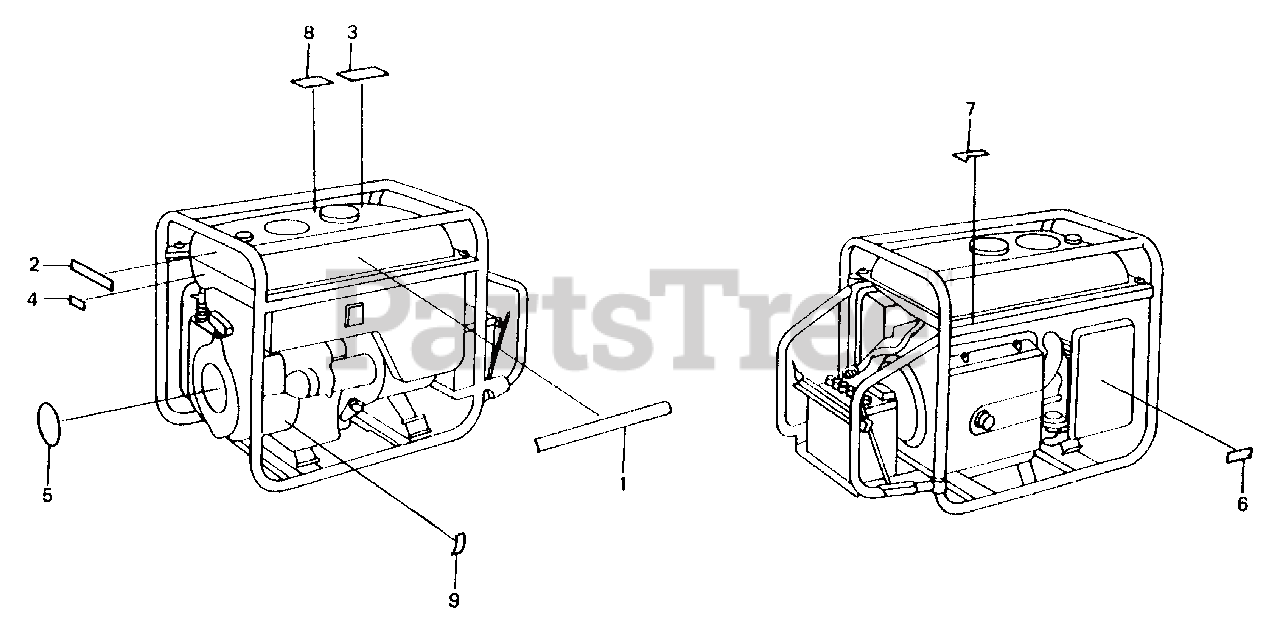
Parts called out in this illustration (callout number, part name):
2	PLATE, CAUTION (NOT AVAILABLE)
3	MARK, CAUTION (ENGLISH/FRENCH)(SPANISH)
4	MARK, CHOKE
5	LABEL, OIL ALERT
6	MARK, AIR CLEANER (ENGLISH)
7	MARK, EX. CAUTION (ENGLISH/FRENCH)
8	MARK, CAUTION (CO)(ENGLISH/FRENCH)(SPANISH)
9	MARK, OIL CAUTION
